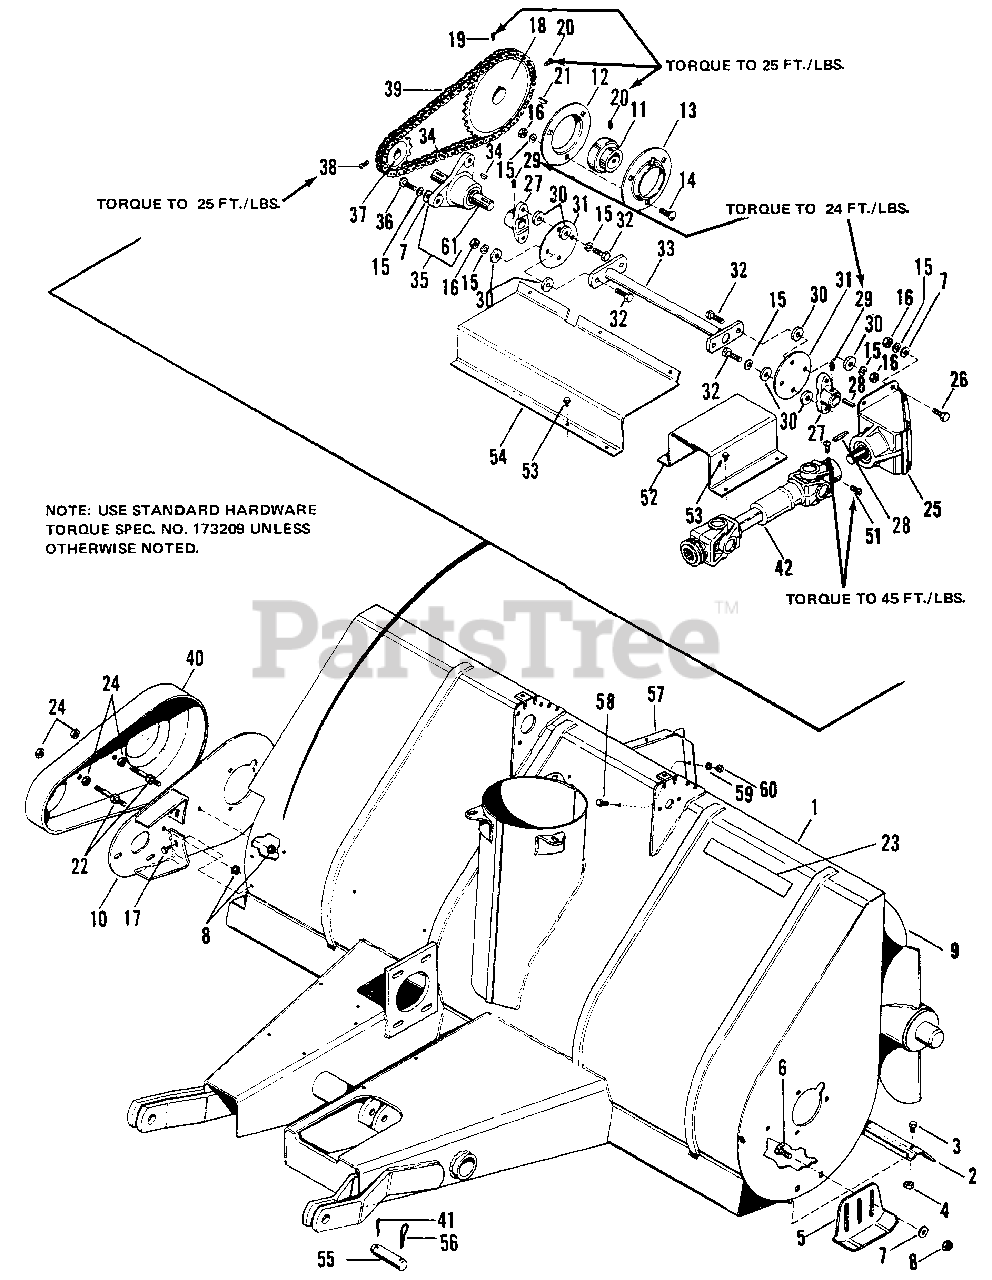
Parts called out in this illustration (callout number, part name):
1	FRAME & BODY ASSY
2	SCRAPER, Blade
3	CAPSCREW, Hex Hd., 5/16-18 x 3/4, Gr. 8
4	NUT, Hex, Full Lock, Jam, 5/16-18
5	SKID & PLATE ASSY
6	CAPSCREW, Hex Hd., 3/8-16 x 1, Gr. 8
7	WASHER, Plain, 3/8
8	NUT, Flange, Hex, Whizlock, 3/8-16
9	ROTOR ASSY
10	SIDE PLATE & BRACKET ASSY
14	BOLT, Rd. Hd., Sq. Nk,. 3/8-16 x 1
15	LOCKWASHER, Spring 3/8
16	NUT, Hex, 3/8-16
17	SCREW, Tapping, 5/16-18 x 1/2
18	SPROCKET, 34 T
19	SCREW, Set, Sq. Hd., Cup Pt., 5/16-18 x 5/8, Gr. 8
20	SCREW, Set, Sq. Hd., Cup Pt., 5/16-18 x 1/2, Gr. 8
21	KEY, Hi-Pro, 5/16 x 1
23	DECAL, Safety
24	NUT, Hex, Full Lock, 3/8-16
25	BOX, Gear, 90 Degree
26	CAPSCREW, Hex Hd., 3/8-16 x 1-1/2
27	FLANGE, Drive Shaft
29	SCREW, Set, Hex, Skt., 3/8-24 x 3/8
